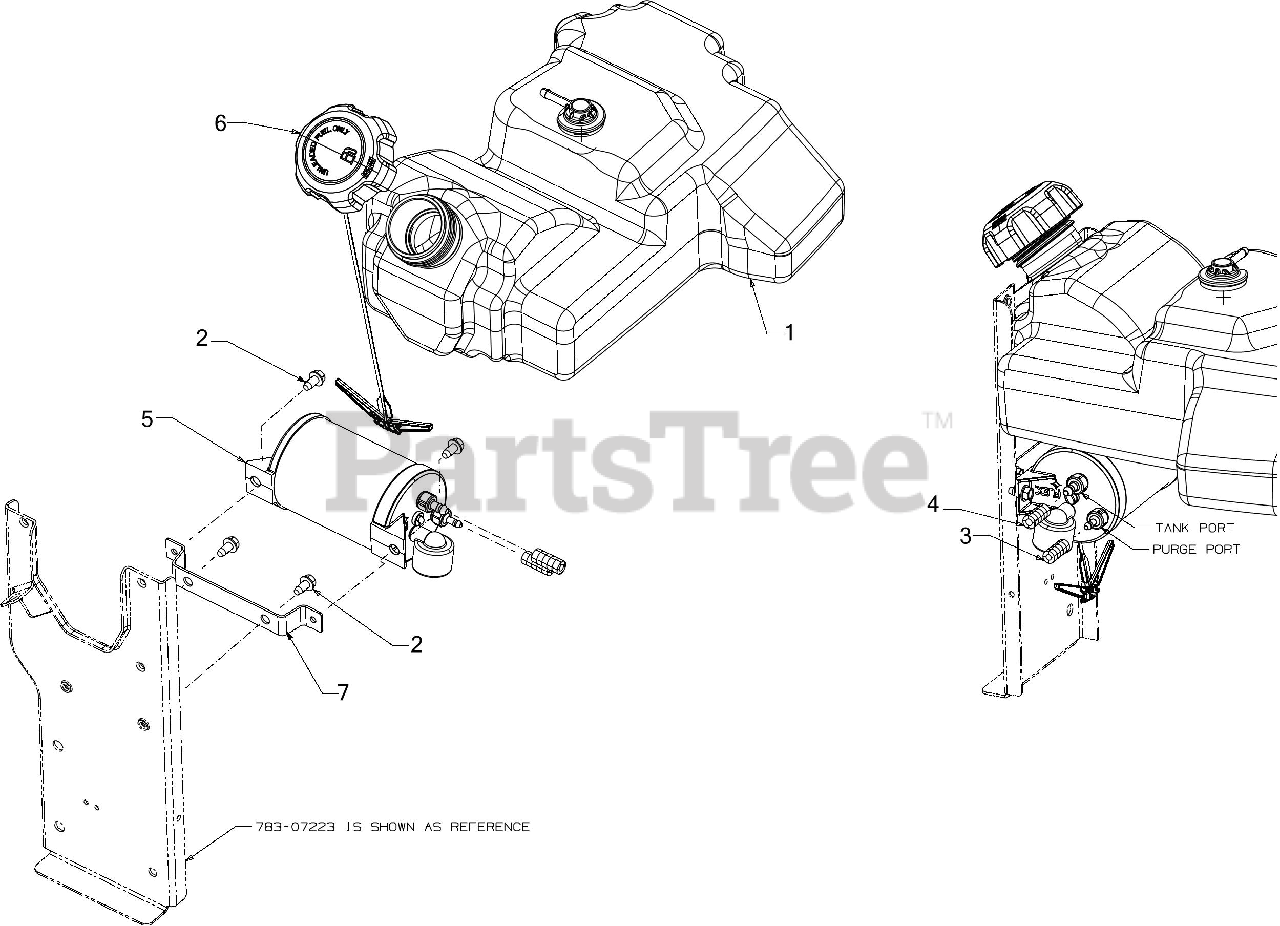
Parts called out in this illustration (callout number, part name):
1	FUEL TANK ASSEMBLY
2	SCREW 1/4-20 X.500
3	FUEL HOSE LOW PERMEATION
4	FUEL HOSE LOW PERMEATION
5	CARBON CANISTER
6	FUEL CAP W/TETHER
